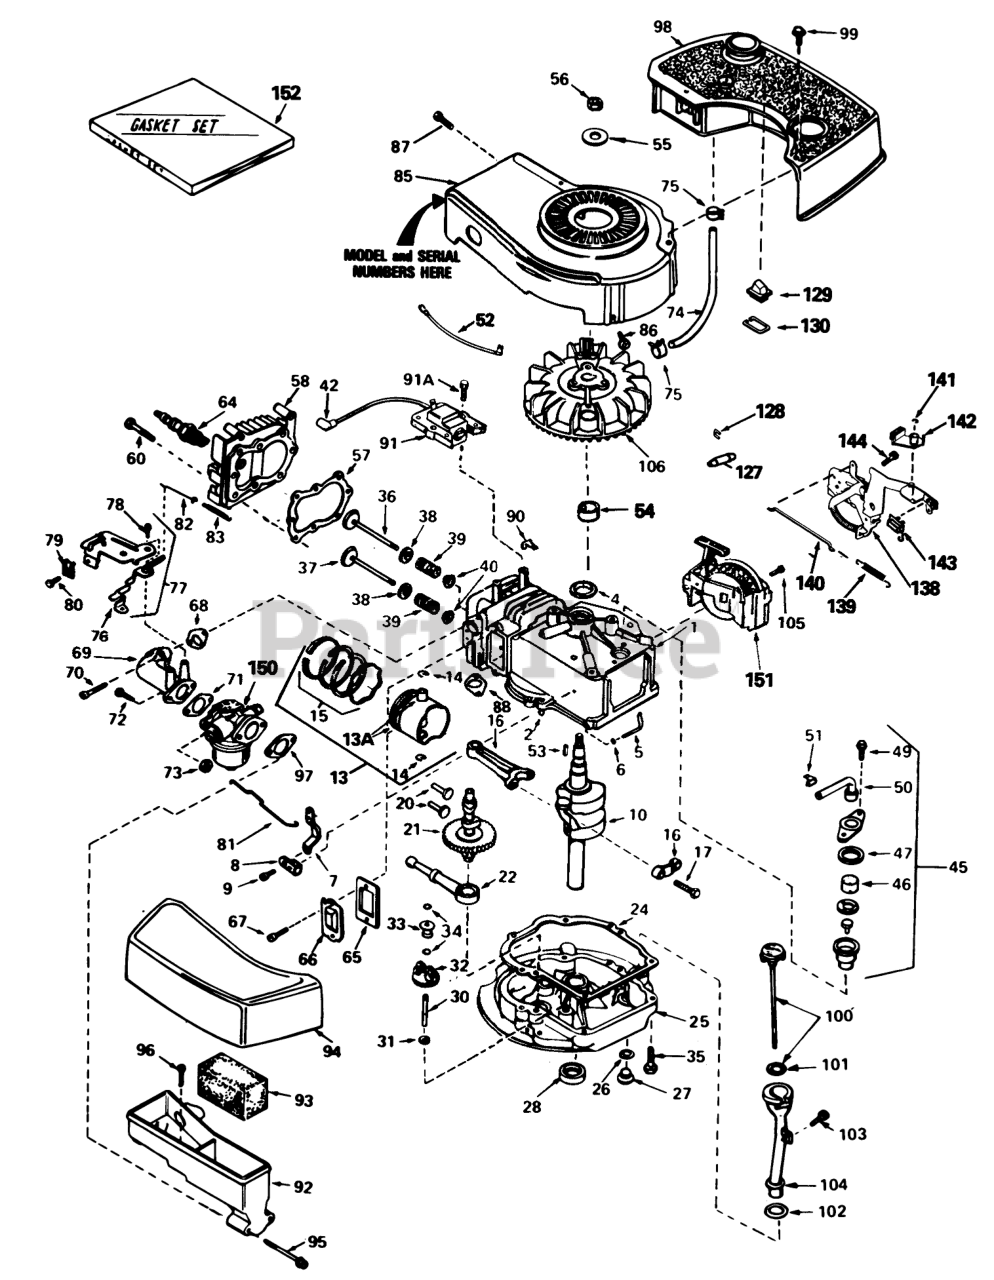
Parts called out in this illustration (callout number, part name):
1	Cylinder Assy. (Inc. #2&4)
2	Pin-Dowel
4	Seal-Oil
5	Rod, Governor (Incl. #6)
6	Washer-Flat
7	Governor Lever
8	Clamp-Lever, Governor
9	Screw
10	Crankshaft
13	Piston, Pin & Ring Assy. (Std.) (Incl. #13A, 14 & 15)
13	Piston, Pin & Ring Assy. (.010 oversize) (Incl. #13A, 14 & 15)
13	Piston, Pin & Ring Assy. (.020 oversize) (Incl. #13A, 14 & 15)
13A	Piston & Pin Assy. (Std.) (Inc. #14)
13A	Piston & Pin Assy. (.010 oversize) (Incl. #14)
13A	Piston & Pin Assy. (.020 oversize) (Inc. #14)
14	Ring-Retaining, Piston Pin
15	Ring Set (Std.)
15	Ring Set (.020" OS)
15	Ring Set (.010" OS)
16	Rod Assy., Connecting (Incl. #17)
17	Bolt-Rod, Connecting
20	Lifter-Valve
21	Camshaft(Mech.Comp. Release)
22	Oil Pump ASM
24	Gasket, Mounting
25	Flange Assy., Mounting (Incl. #26 thru 30)
26	Gasket-Oil Drain
27	Plug Oil Drain
28	Seal Oil
30	Shaft-Governor
31	Washer-Flat
32	Gear Assy., Governor (Incl. #31)
33	Spool-Governor
34	Ring-Retaining
35	Screw (1/4-20 x 1-1/4)
36	Valve, Intake (Std.) (Incl. #40)
36	Valve, Intake (1/32" oversize)(Incl. #40)
37	Valve, Exhaust (Std.) (Incl. #40)
37	Valve, Exhaust (1/32" oversize)(Incl. #40)
38	Cap-Upper Valve Spring
39	Spring-Valve
40	Cap-Valve, Spring
42	Cover-Spark Plug
45	Breather Assy. (Incl. #46 thru 51)
46	Element-Breather
47	Gasket-Breather
49	Screw (10-24 x 9/16)
50	Tube, Breaker
51	Clip, Breather
52	Ground Wire
53	Key-Flywheel
55	Washer-Belleville
56	Nut-Flywheel
57	63573 GIL 42 SNWTHW
58	Head-Cylinder
60	Screw (5/16-18x1-1/2)
64	Plug, Spark (J17LM or equiv.)
64	Plug, Spark (Champion RCJ-8)
65	Gasket-Breather
66	Cover-Valve
68	Gasket-Intake
69	Pipe, Intake (Incl. #68)
70	Screw (1/4-20 x 1)
71	Gasket-Carburetor
72	Screw (1/4-28 x 7/8)
73	Nut and Lock Washer (1/4-28)
74	Line-Fuel
75	Clamp-Line, Fuel
76	Lever Control
77	Control Assy., Speed (Incl. #76 & 78)
78	Screw, Hex Washer Hd Shoulder Self-Tap
79	Conduit
80	Screw (10-32 x 3/8)
81	Link-Throttle
82	Link Governor Spring
83	Spring Governor
85	Housing-Blower
86	Screw (1/4-20x19/32)
87	Screw (10-24 x 9/16)
88	Gasket Exhaust
90	Clip-Wire
91	Lamination & Coil Assy. (Solid State) (Incl. #42)
91A	Screw
92	Body Air Cleaner
93	Filer, Air
94	Cove, Air Cleaner
95	Screw Fil Hd.
96	Screw, Hex Hd.
97	Gasket-Air Cleaner
98	Tank, Fuel
99	Screw (10-32 x 35/64)
100	Dipstick, Oil (Incl. #101)
103	Screw (10-32 x 1/2)
104	Tube-Oil Fill
105	Screw (1/2-20x5/8)
106	Flywheel
127	Coupling, Starter Rope
128	Staple, Rope Retainer (Strip of 25 Pieces)
129	Pulley Assy., Starter
130	Retainer, Pulley
138	Bracket Assy.
139	Spring-Extension
140	Link-Control
141	Ring-Retaining
142	Lever-Brake
143	Terminal
144	Screw-Hex. Hd.
150	Carburetor (Incl. #71)
151	Starter, Sidemount rewind
152	Gasket Set (Incl. Items Marked )
